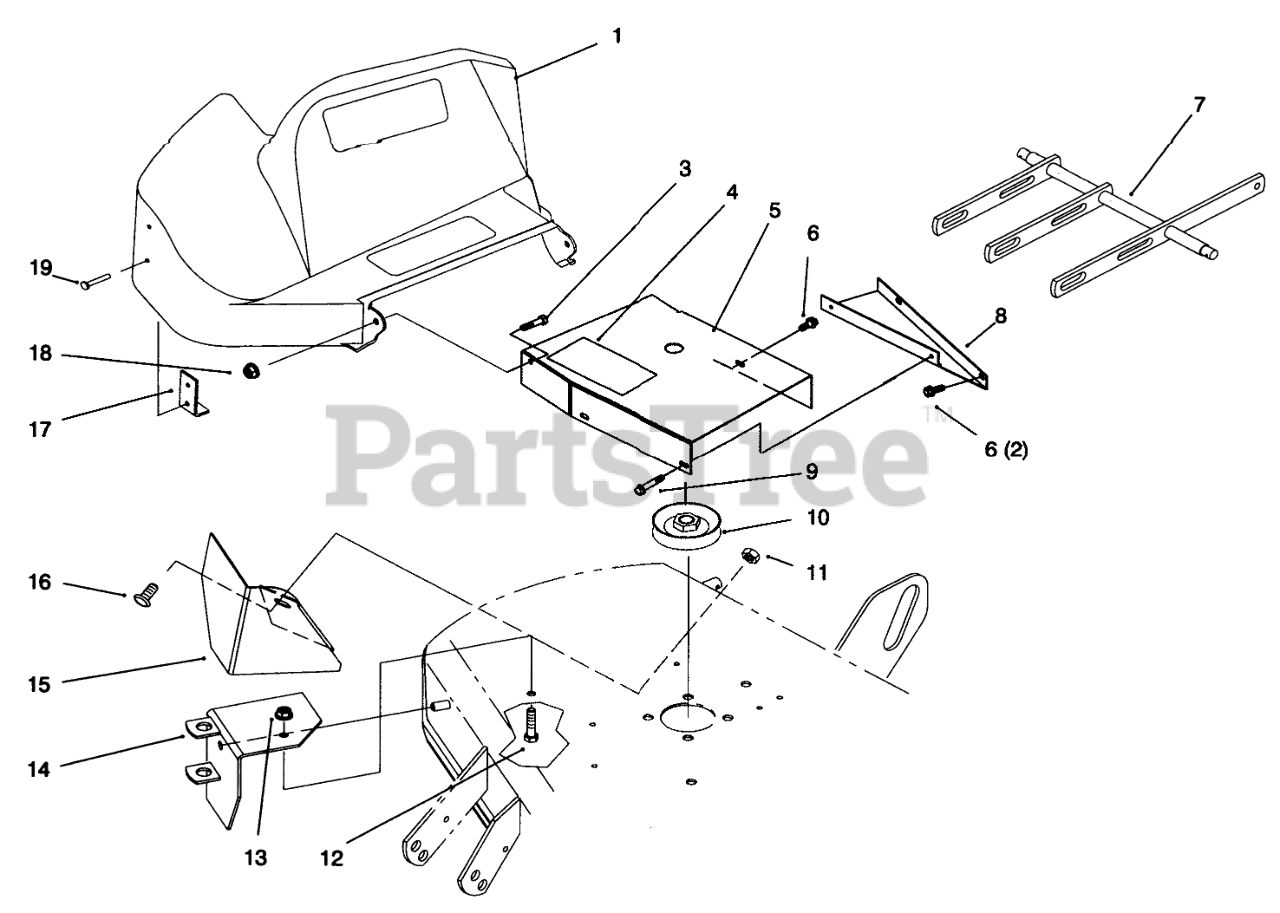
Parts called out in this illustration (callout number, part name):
1	SHIELD-BELT
3	SCREW-HH
4	DECAL-DANGER
5	Inner Shield Assembly (Incl. Ref. #4)
6	SCREW-HHF
7	Bar-Leveler
8	48" ADAPTOR SHIELD B
9	SCREW-HWH
10	PULLEY
11	NUT-LOCK, NI
12	SCREW-HH
13	NUT-HF
14	PIVOT SUPPORT ASM
15	48" DEFLECTOR B
16	SCREW-CARR
17	BRACKET-SUPPORT, SHIELD
18	NUT-LOCK, NI
19	RIVET-POP
